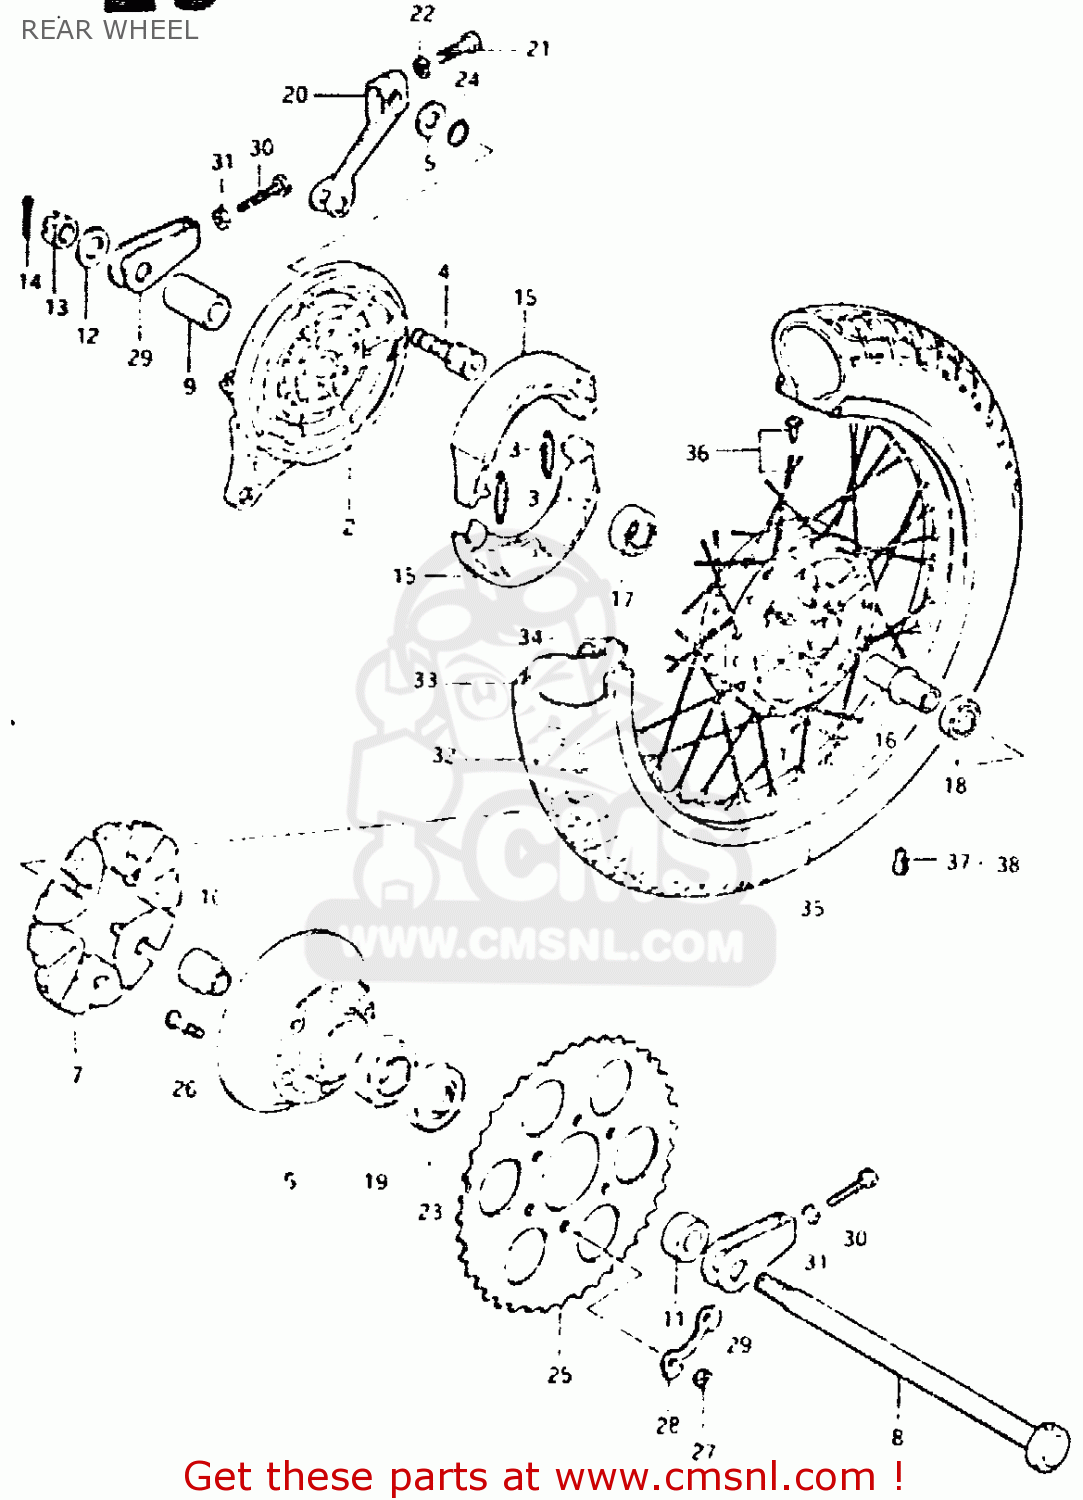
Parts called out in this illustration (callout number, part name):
1	DRUM,REAR HUB
2	PANEL,REAR HUB
3	SPRING,BRAKE SHOE
4	CAM,FRONT BRAKE
5	WASHER (15X24X1.6)
6	DRUM,REAR SPROCKET MOUNT
7	CUSHION,REAR DRUM
8	AXLE,REAR
9	SPACER(17.5X28X44.8)
10	SPACER,REAR HUB BEARING
11	SPACER(17X30.5X22.3)
12	WASHER (17X30X3.2)
13	NUT
14	PIN,COTTER
15	SHOE SET,BRAKE (MCA)
16	SPACER
17	BEARING
18	BEARING
19	BEARING
20	LEVER,RR BRAKE CAM
21	BOLT
22	LOCK WASHER
23	SEAL,OIL(30.5X52X8)
24	O-RING,BOSS
25	SPROCKET,REAR (NT:43)
26	BOLT
27	NUT
28	WASHER
29	ADJUSTER,CHAIN
30	BOLT
31	NUT
32	TIRE
33	TUBE ASSEMBLY,WHEEL,INNER
34	PROTECTOR,WHEEL,INNER
35	RIM,REAR WHEEL
36	SPOKE SET,REAR WHEEL
37	BALANCER,WHEEL (B)
38	BALANCER,WHEEL (30G)
